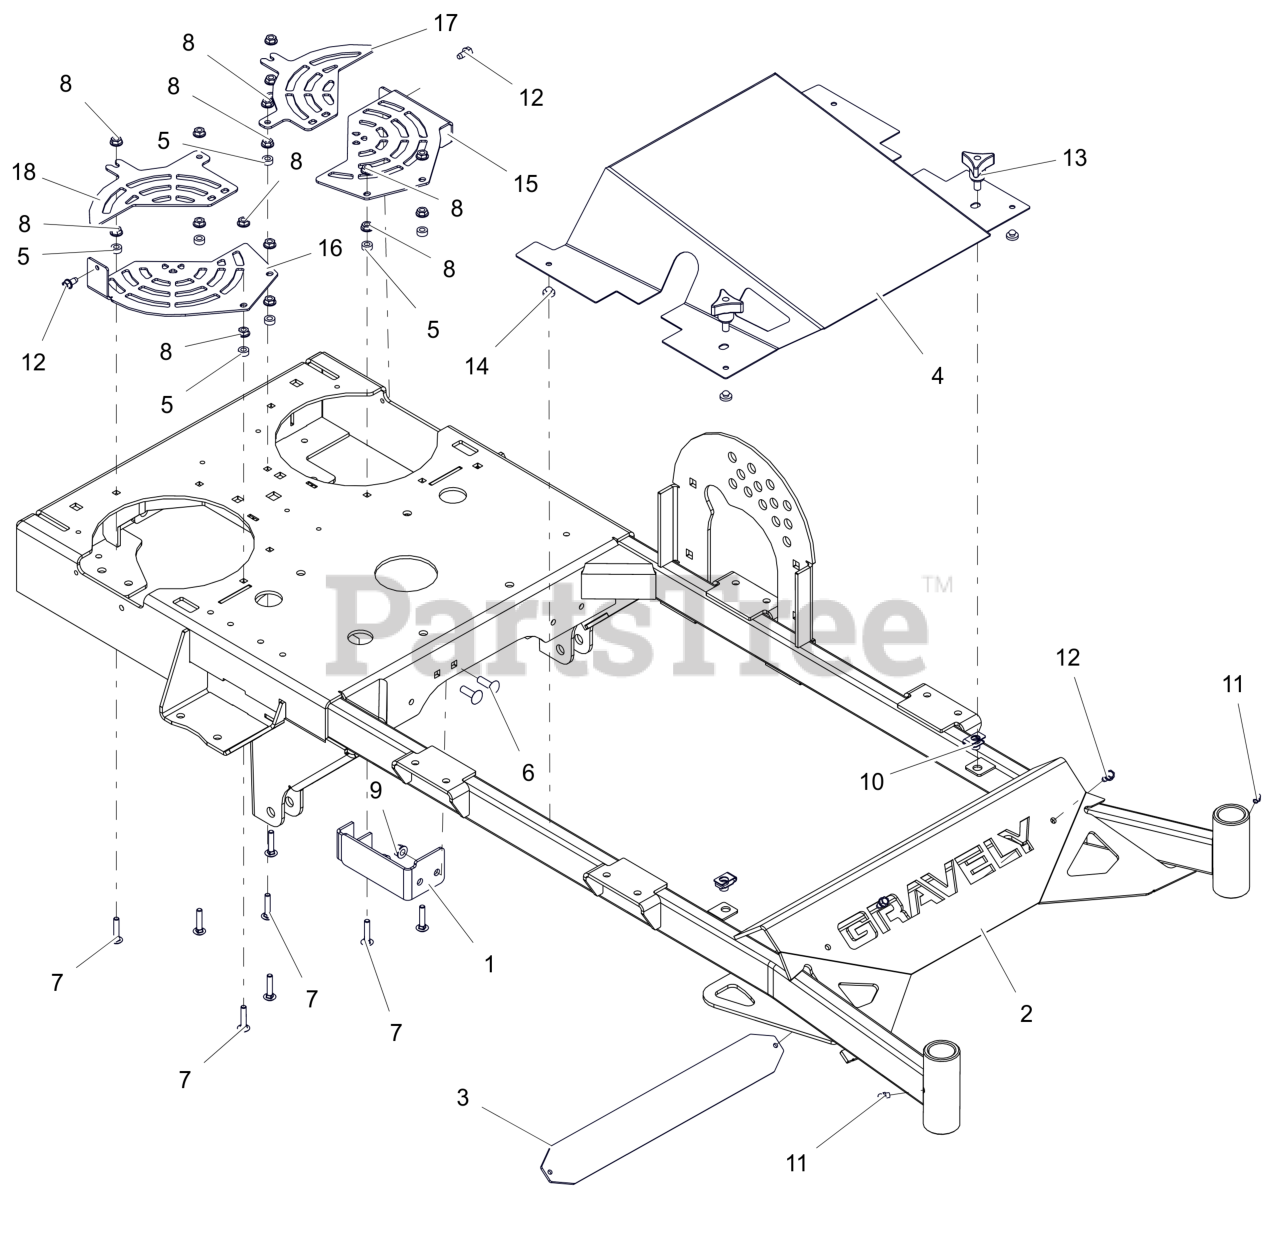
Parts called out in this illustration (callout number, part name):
1	WLDMT, CLUTCH STOP
2	WLDMT, FRAME 36" PRO WLK (RED)
3	BACKER, NAMEPLATE
4	SHIELD, FRONT 36" PRO-WALK (RED)
5	BSHG-SLV .265X.500X.219
6	BLT,RHSSN .31-18X1.00 G5 ZCC
7	BTL,RHSN .250-20 X 1.25 G5 ZCC
8	NUT-LK-CTR-FLG .25-20 ZC120
9	NUT,LK-CTR-FLG .31-18 GF ZCC
10	NUT-CLIP RETAINER 5/16-18X.56
11	FTG-LUBE .25-28X.256 SST
12	SCR-TAP .25-20X.50 HWH ZCC
13	KNOB,WING STUD 5/16-18 X .75
14	BUMPER GROMMET
15	GUARD, LH FAN - 36" (RED)
16	GUARD-RH FAN - 36"- RED
17	GUARD, LH FAN - 36" (RED)
18	GUARD, RH FAN - 36" (RED)
